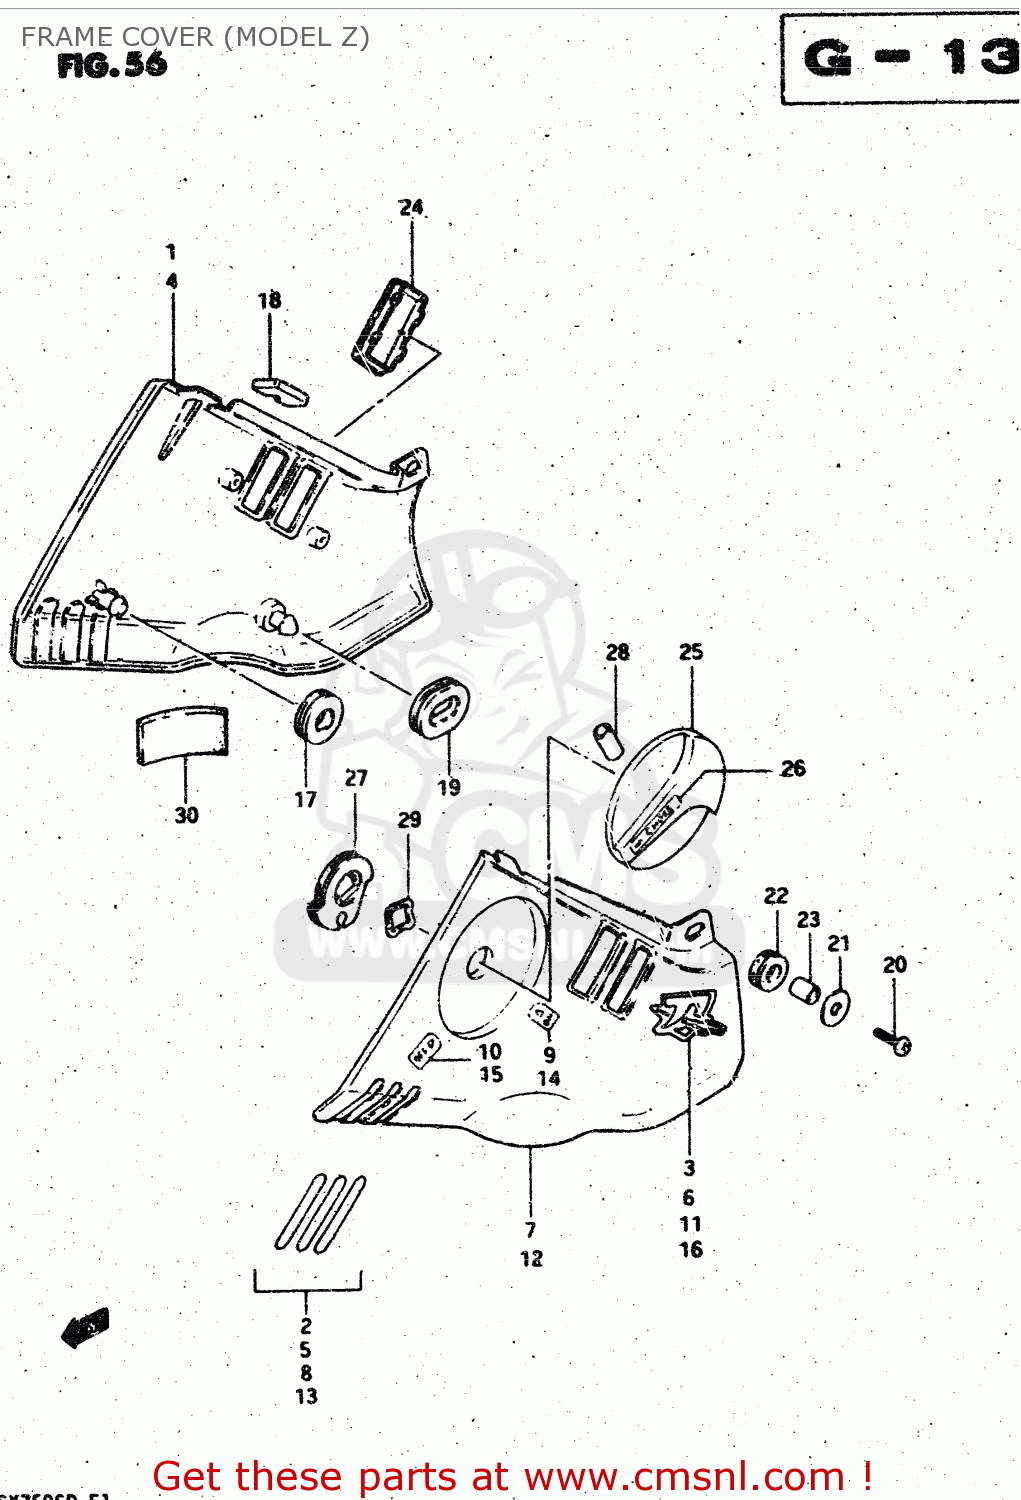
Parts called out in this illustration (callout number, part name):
1	COVER SET,FRAME,R(SILVER)
2	LABEL,FRAME COVER DENT
3	EMBLEM
4	COVER, FRAME RH (RED)
5	LABEL,FRAME COVER DENT
6	EMBLEM,FRAME COVER
7	COVER SET,FRAME,L(SILVER)
8	LABEL,FRAME COVER
9	LABEL,CHOKE ON
10	LABEL,CHOKE OFF
11	EMBLEM
12	COVER, FRAME LH (RED)
13	LABEL,FRAME COVER
14	LABEL,CHOKE ON
15	LABEL,CHOKE OFF
16	EMBLEM,FRAME COVER
17	CUSHION
18	CUSHION
19	CUSHION
20	SCREW
21	WASHER
22	CUSHION
23	SPACER(6.1X9X7.5)
24	CAP,FRAME COVER SWITCH HOLE
25	LEVER,CHOKE CABLE
26	LABEL,CHOKE LEVER
27	HOLDER, STARTER
28	TUBE,CHOKE CABLE LEVER
29	WASHER
30	PAD
